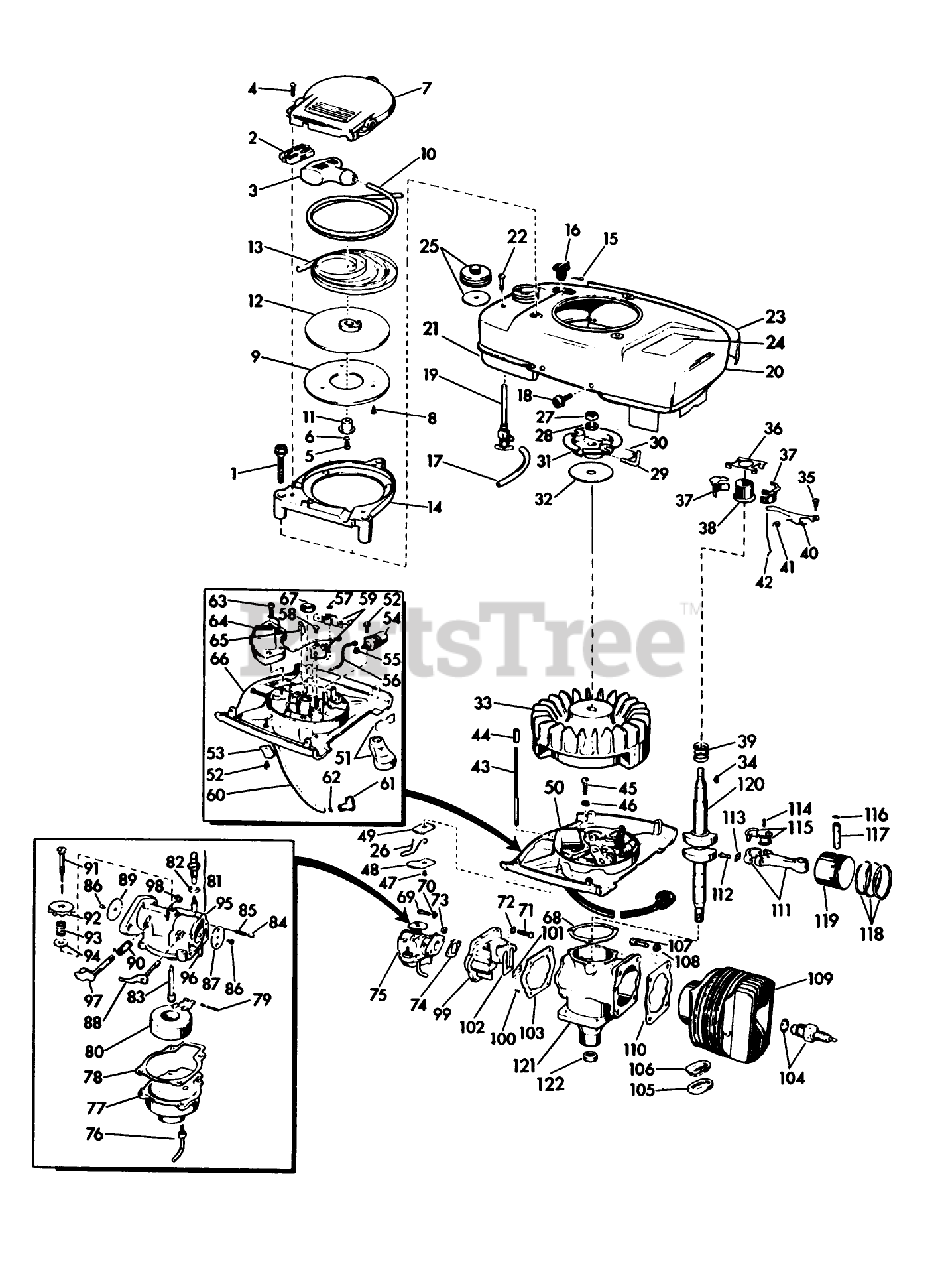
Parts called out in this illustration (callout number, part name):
9	Plate-Pulley
13	RECOIL SPRING
15	Cotter Pin-Choke Knob
16	KNOB, CHOKE BAR
18	SCREW S
19	VALVE&SCREEN SM
24	Decal-Instruction
29	PIN - STARTER
38	COLLAR S
40	GOVERNER LEVER AY
41	WEAR BLOCK S
42	GOVERNOR ROD S
47	Screw Shut-off Switch
59	BREAKER AY. S
61	Cover-Rubber
68	GASKET S
69	SCREW S
73	STOP NUT
74	GASKET S
86	Screw-Choke Disc
87	Disc-Choke
88	CHOKE SHAFT&LVR AY
90	SPRING
91	NEEDLE AY. S
93	Spring-Ndl. Adj.
101	PLATE-BACKUP, REED
104	Spark Plug
110	GASKET S
115	LINER ASM
116	RING-RETAINING
